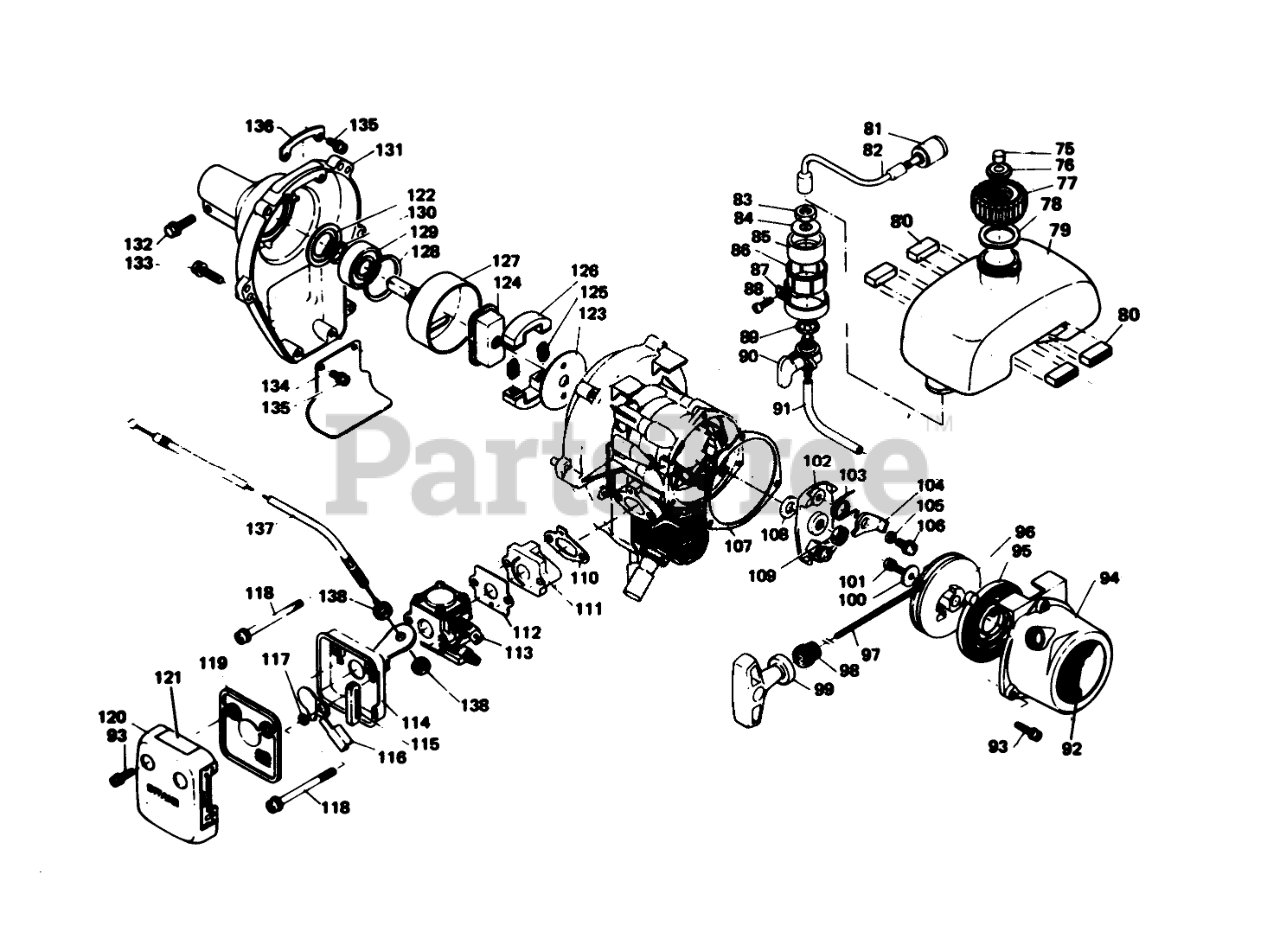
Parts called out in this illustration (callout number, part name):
75	Filter
76	Check Valve
77	Cap, Fuel Tank
78	Gasket-Fuel Tank Cap
79	Fuel Tank
80	Cushion
81	Fuel Strainer
82	Fuel Pipe
84	WASHER
86	COLLAR
87	CLAMP
88	SCREW
89	GASKET
90	FUEL VALVE ASM
91	FUEL PIPE
92	Decal
93	SCREW
94	Starter Case
95	REWIND SPRING
96	RECOIL DRUM
97	Rope-Starter
98	Rope Guide
99	Starter Handle
100	Washer
101	Screw
102	PAWL CATCHER
103	Ratchet Spring
104	RATCHET
105	RATCHET SPACER
106	SCREW
107	STARTER CASE GASKET
108	Spacer
109	Washer
110	GASKET
111	Insulator
112	GASKET
113	Carburetor Assy.
114	Case Air Cleaner
115	GROMMET
116	Choke Shutter
117	CHOKE SHUTTER SPACER
118	Screw
119	AIR FILTER
120	AIR CLEANER COVER
121	Decal, Fuel Valve
122	Stopper
123	Side Plate, Clutch
124	Clutch Boss
125	Clutch Spring
126	CLUTCH SHOE
127	Clutch Drum
128	Circlip
129	Ball Bearing
130	Circlip
131	Fan Cover
133	Screw
134	Bracket
135	SCREW
137	Throttle Cable
